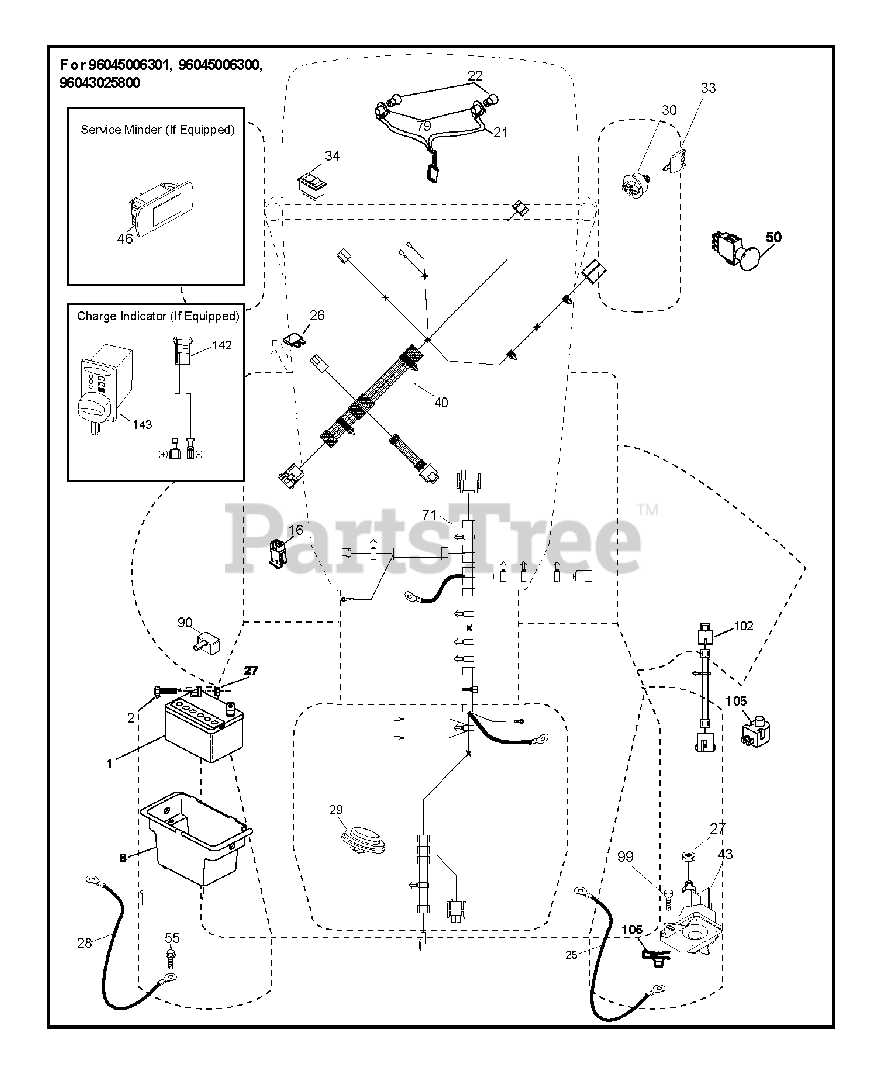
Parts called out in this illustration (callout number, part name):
1	Battery 12 Volt 25 Amp
2	BOLT.HEX.1/4.X.3/4.DICHROMATE
8	BOX.BATTERY.MNT.REAR.L
16	SWITCH INTERLOOK PUSH-IN
21	HARNESS.LIGHT W/4152J BULBS
25	CABLE.BATT.RED.8GA.17
26	FUSE 20AMP
28	CABLE.GROUND.REAR.BATTERY.8G
29	SWITCH.SEAT.DELTA.OPC.
30	SWITCH.IGN.DELTA.W.LGH.ROS
33	KEY.CHAIN.BLISTER.PACK.GEN.INT
33	KEY.CHAIN.BLISTER.PACK.GEN.USA
40	HARNESS.TEX.DASH.ELEC.REAR BAT
46	GUAGE.SRVCMNDR.HRMTR.
50	RP SWITCH.PTO.TERMINAL.STD.RED
55	SCREW 5/16"
71	HARNESS.CHASSIS.RRBATT.RDYSTRT
79	BULB HOLDER ASM.
90	COVER.TERMINAL.BATTERY
99	SCREW HEXWSHR 1/4-20X3/4
102	HARNESS PIGTAIL PCH TEX ROS
105	REVERSE SWITCH
106	1/4-20 U NUT
